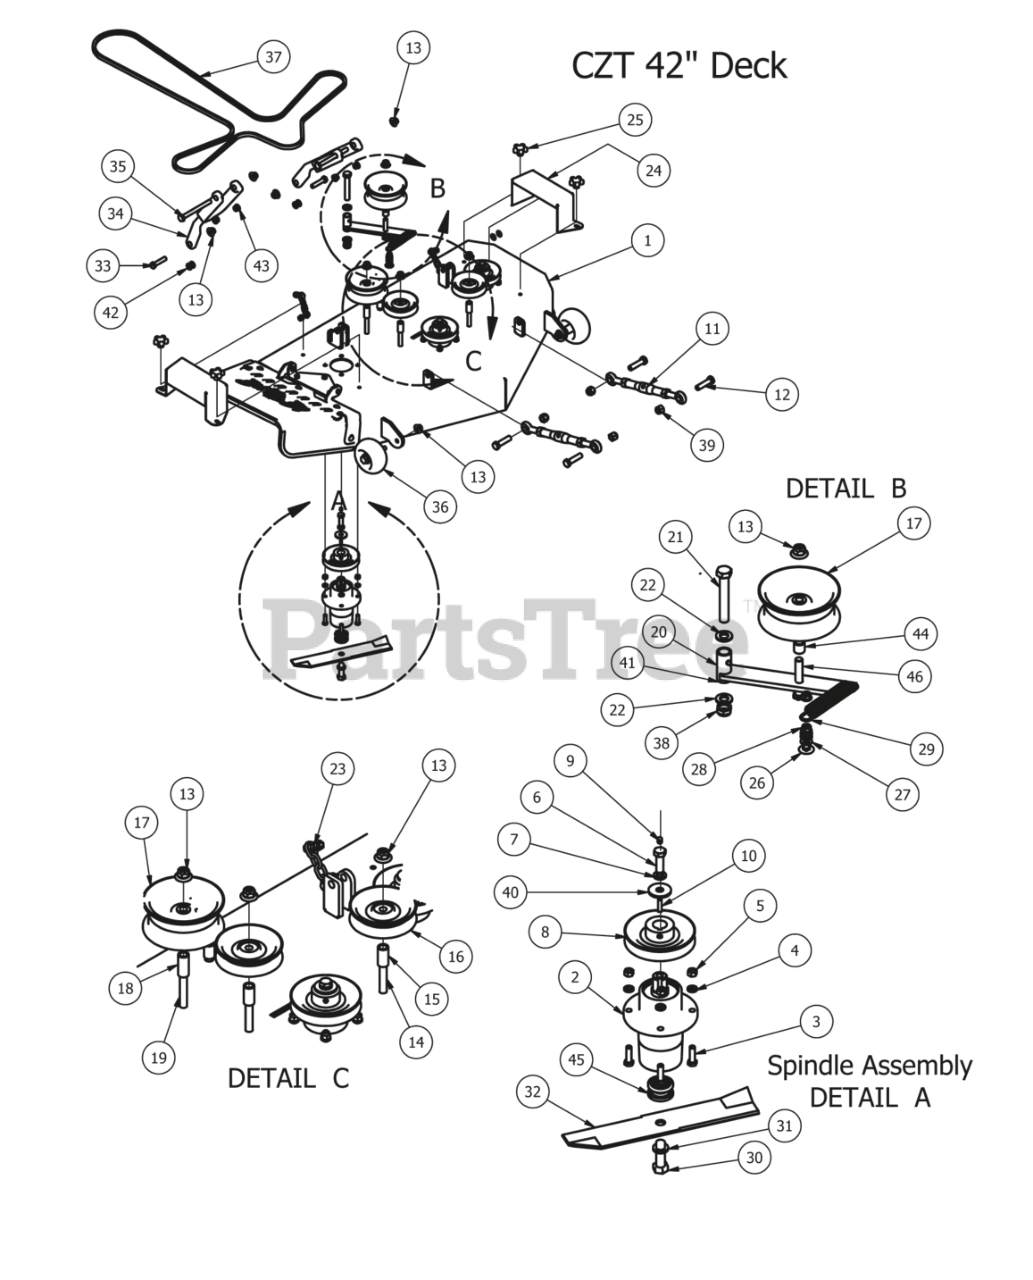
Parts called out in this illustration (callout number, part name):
1	42 CZT Deck
2	Blade Hub Spindle ('04 and Up)
3	3/8" x 1 1/4" Hex Bolt
4	3/8" Lock Washer
5	3/8" Hex Nut
6	1/2-20 x 1 1/2" GR 5 Bolts
7	1/2" Lock Washer
8	5" Deck Pulley
9	3/8" Set Screw
10	1/4" x 1" Key
11	Turnbuckle (Top Link)
12	5/8" x 2 1/2" Hex Bolt
13	1/2-13 Nylon Flange Nut-Orange
14	1/2 x 3 1/2 Flange Bolt Grade 8
15	Pup Pulley Spacer
16	4 3/4" Idler Pulley
17	5 3/4" Deck Idler Pulley
18	1 3/4" Pulley Spacer
19	1/2-13 x 3 1/2 GR 5 Hex Bolt
20	Deck Idler Bracket
21	5/8" x 4" Hex Bolt
22	.635 ID Plastic Washer
23	ZT Deck Hanger Chain Assembly
24	1/2 Metal Spindle Cover 48/50"
25	5/16" Knob
26	3/8 x 1-1/2 Carriage Bolt
27	3/8" Flat Washer
28	3/8" Nylock Flange Nut
29	Deck Idler Spring
30	5/8-18 x 1-1/2" GR 8 Hex Bolt
31	5/8" Lock Washer
32	42 inch High Lift Fusion Blade
33	1/2-13X 2-1/4 GR Hex Bolts
34	Deck Arm Assembly
35	1/2" x 5 1/2" Bolt
36	Deck Wheel
38	5/8" Nylock (1/2 Jam)
39	5/8 Std NC Nylock Nut
40	1/2 Belleville Washer
41	Deck Idler Assembly Components 13,17,20,44,46
42	Flange for Lower Deck Arm
43	Flange Bushing For Deck Arm upper
44	3/4 OD x 1/2 ID x 3\4 Length
45	Spindle Bearing
46	1/2-13 x GR 5 Hex Bolt Zinc
